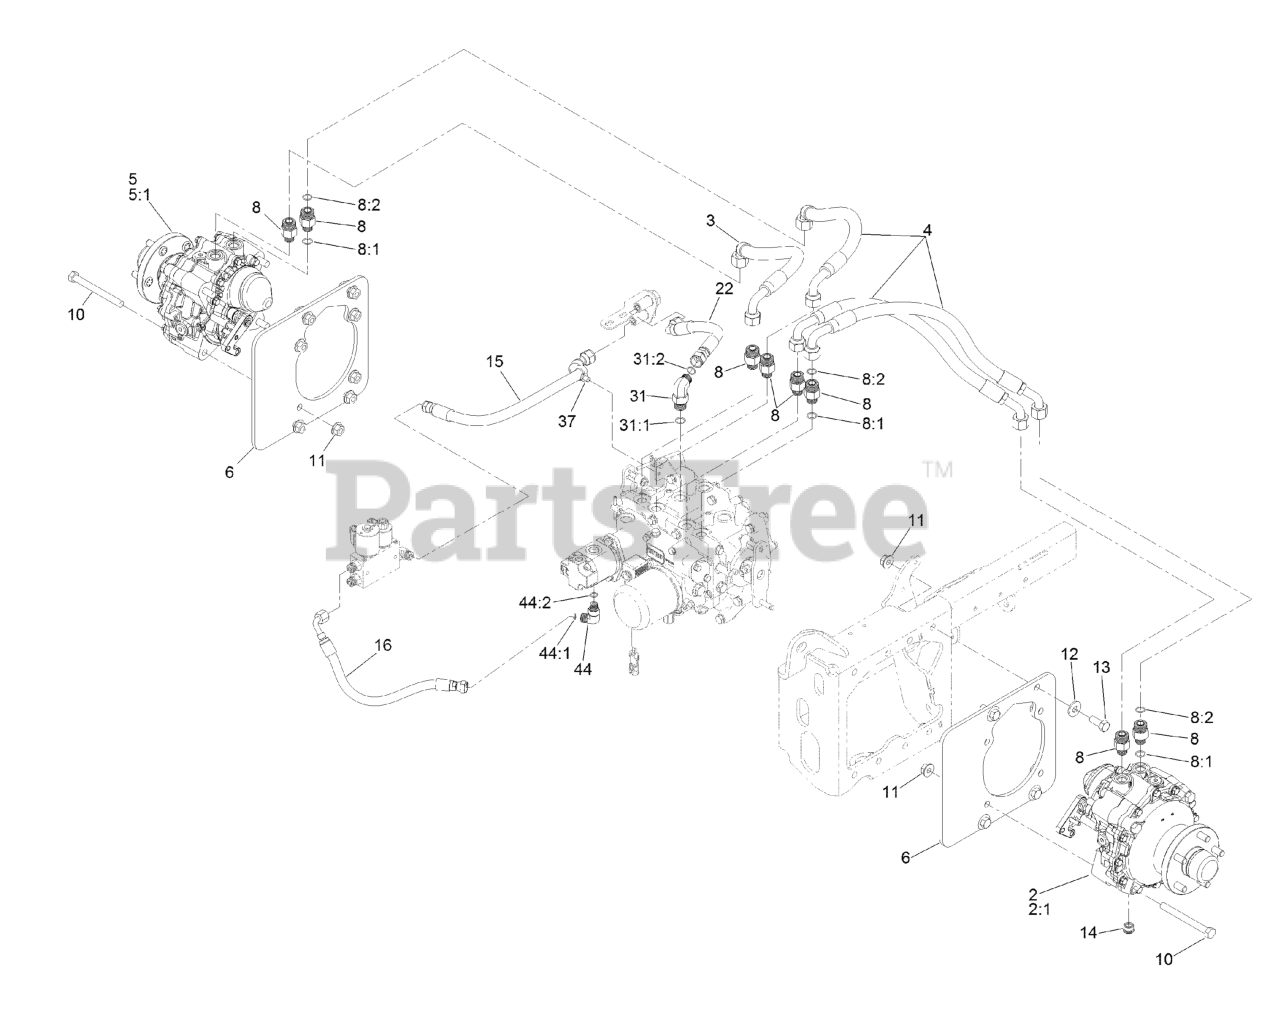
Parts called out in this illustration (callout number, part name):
2	MOTOR-HYD, LH
2:1	5 STUD WHEEL HUB KIT
3	HOSE ASM
4	HOSE ASM
5	MOTOR-HYD, RH
5:1	5 STUD WHEEL HUB KIT
6	PLATE-MOTOR
8	FITTING-STRAIGHT
8:1	O-RING
10	SCREW-HH
11	NUT-HHF
12	WASHER-SPRING
13	SCREW-HH
14	PLUG-MAGNETIC
15	HOSE ASM
16	HOSE ASM
22	HOSE ASM
31	FITTING-ELBOW, 90 DEG
31:1	O-RING
31:2	O-RING
37	CLIP-TIE
44	FITTING-ELBOW, 90 DEG
44:1	O-RING
44:2	O-RING
